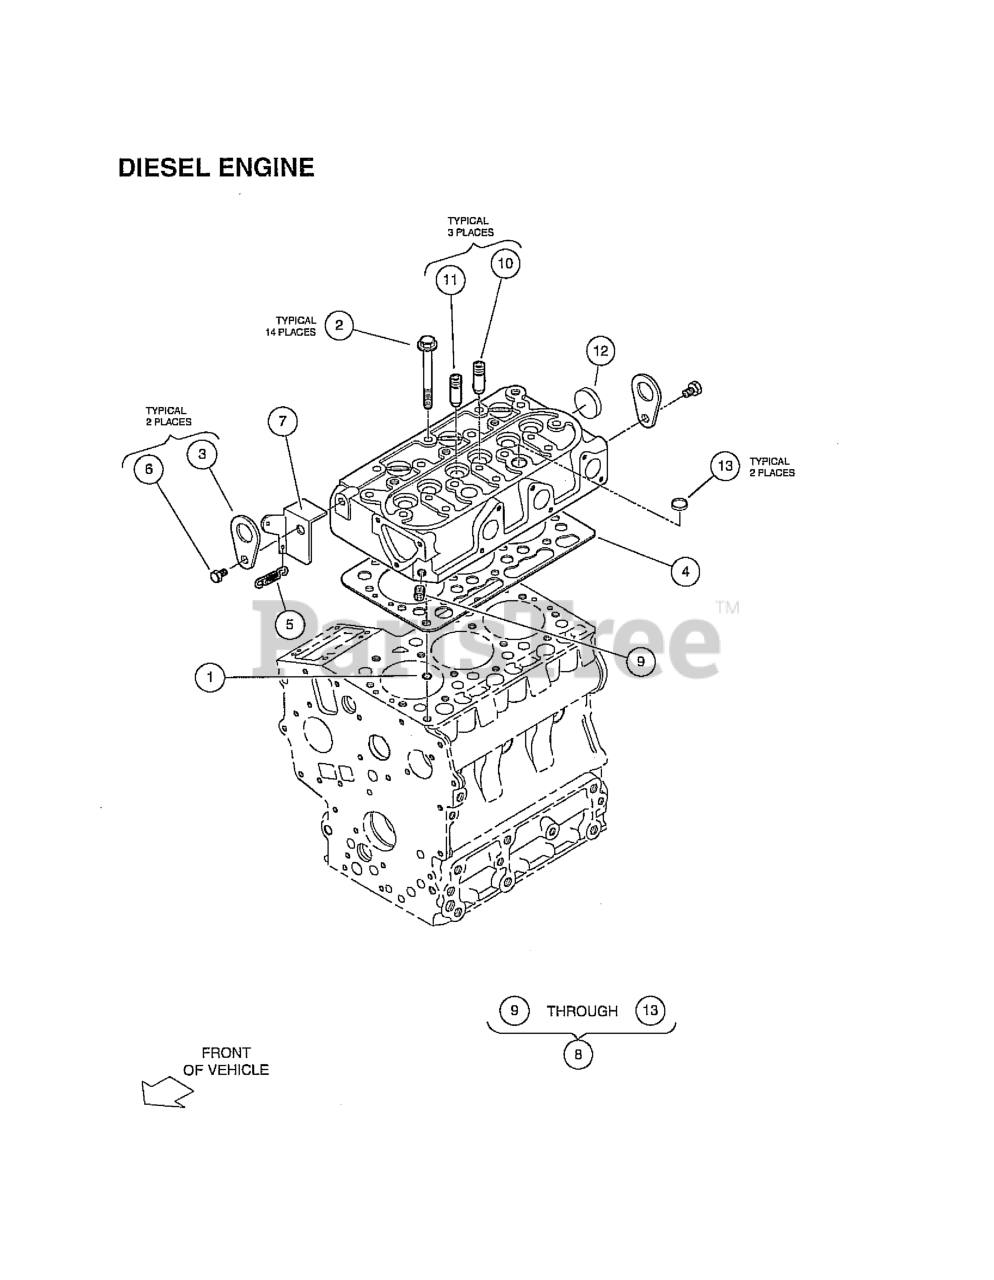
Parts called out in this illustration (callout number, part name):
1	O-RING, 8 X 7
2	BOLT, CYLINDER HEAD
3	HOOK, ENGINE
4	GASKET, CYLINDER HEAD
5	SPRING, START
6	BOLT, ENGINE HOOK
7	STAY, CYLINDER HEAD
8	PLUG-CYL HEAD
10	PLUG, 3/32" NPT
11	GUIDE, EXHAUST VALVE
12	GUIDE, INLET VALVE
13	CAP, SEALING, HEAD
14	CAP, SEALING, HEAD, TOP
